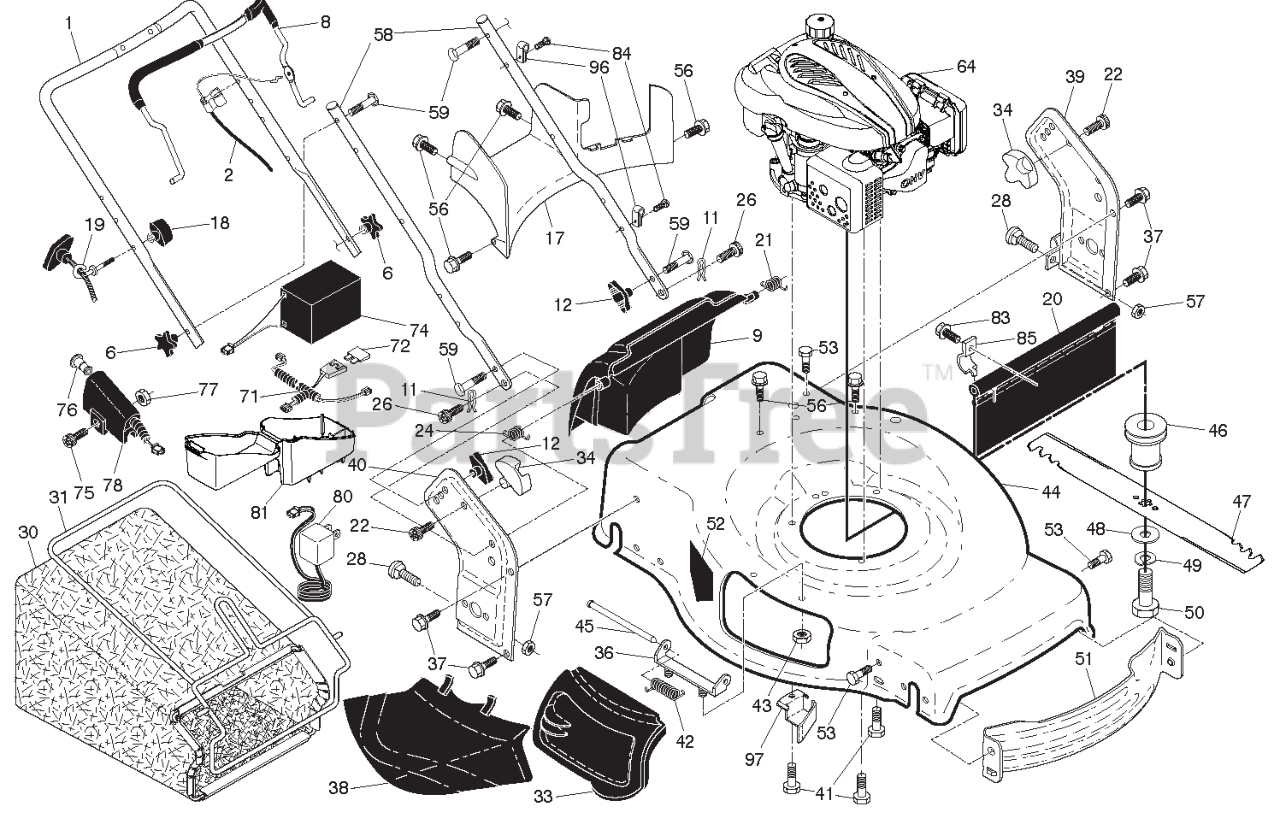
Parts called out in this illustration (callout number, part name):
1	UPPER HANDLE ASSEMBLY
2	CABLE, ENGINE ZONE CONTROL
6	Handle Knob
8	CONTROL BAR
9	REAR DOOR ASSEMBLY
11	HAIRPIN, DOOR/HANDLE PIVOT
12	HANDLE KNOB, STANDARD
17	REAR BAFFLE
19	ROPE GUIDE
20	REAR SKIRT
21	SPRING, REAR DOOR, LH, BLACK
22	SCREW, PANHEAD, TORX #20
24	SPRING, REAR DOOR, RH, GREY
26	SCREW, REAR DOOR/HANDLE PIVOT
28	BOLT, CARRIAGE
30	GRASSBAG
31	FRAME, GRASSBAG
33	MULCHER DOOR
34	BRACKET, GRASSBAG
36	Hinge Bracket Assembly
37	BOLT.5/16-18HEX.WHS.HD.LCKSERR
38	DISCHARGE DEFLECTOR
39	HANDLE BRACKET, LH
40	HANDLE BRACKET, RH
41	Screw, Hex Head, Threaded, Rol
42	Spring, Torsion
43	LOCKNUT, HEX 1/4-20
44	KIT, LAWN MOWER HOUSING
45	Rod, Hinge
46	BLADE ADAPTOR
48	Hardened Washer
49	Helical Lockwasher
50	Screw, Hex Head, Grade 8 3/8-2
51	FRONT BAFFLE
52	DECAL, WARNING
53	BOLT.5/16-18HEX.WHS.HD.LCKSERR
56	Screw, Rear Baffle
57	NUT, HEX
59	Handle Bolt
64	ENGINE,LNCN T322002897-2172008
71	HARNESS, WIRING
72	FUSE, 40 AMP
74	BATTERY
78	ELECT START (W/SWITCH & HSNG)
80	CHARGER
81	BOX, BATTERY
84	FASTENER, PUSH
85	MOUNTING BRACKET, REAR SKIRT
96	Clip, Cable
97	BELT KEEPER
